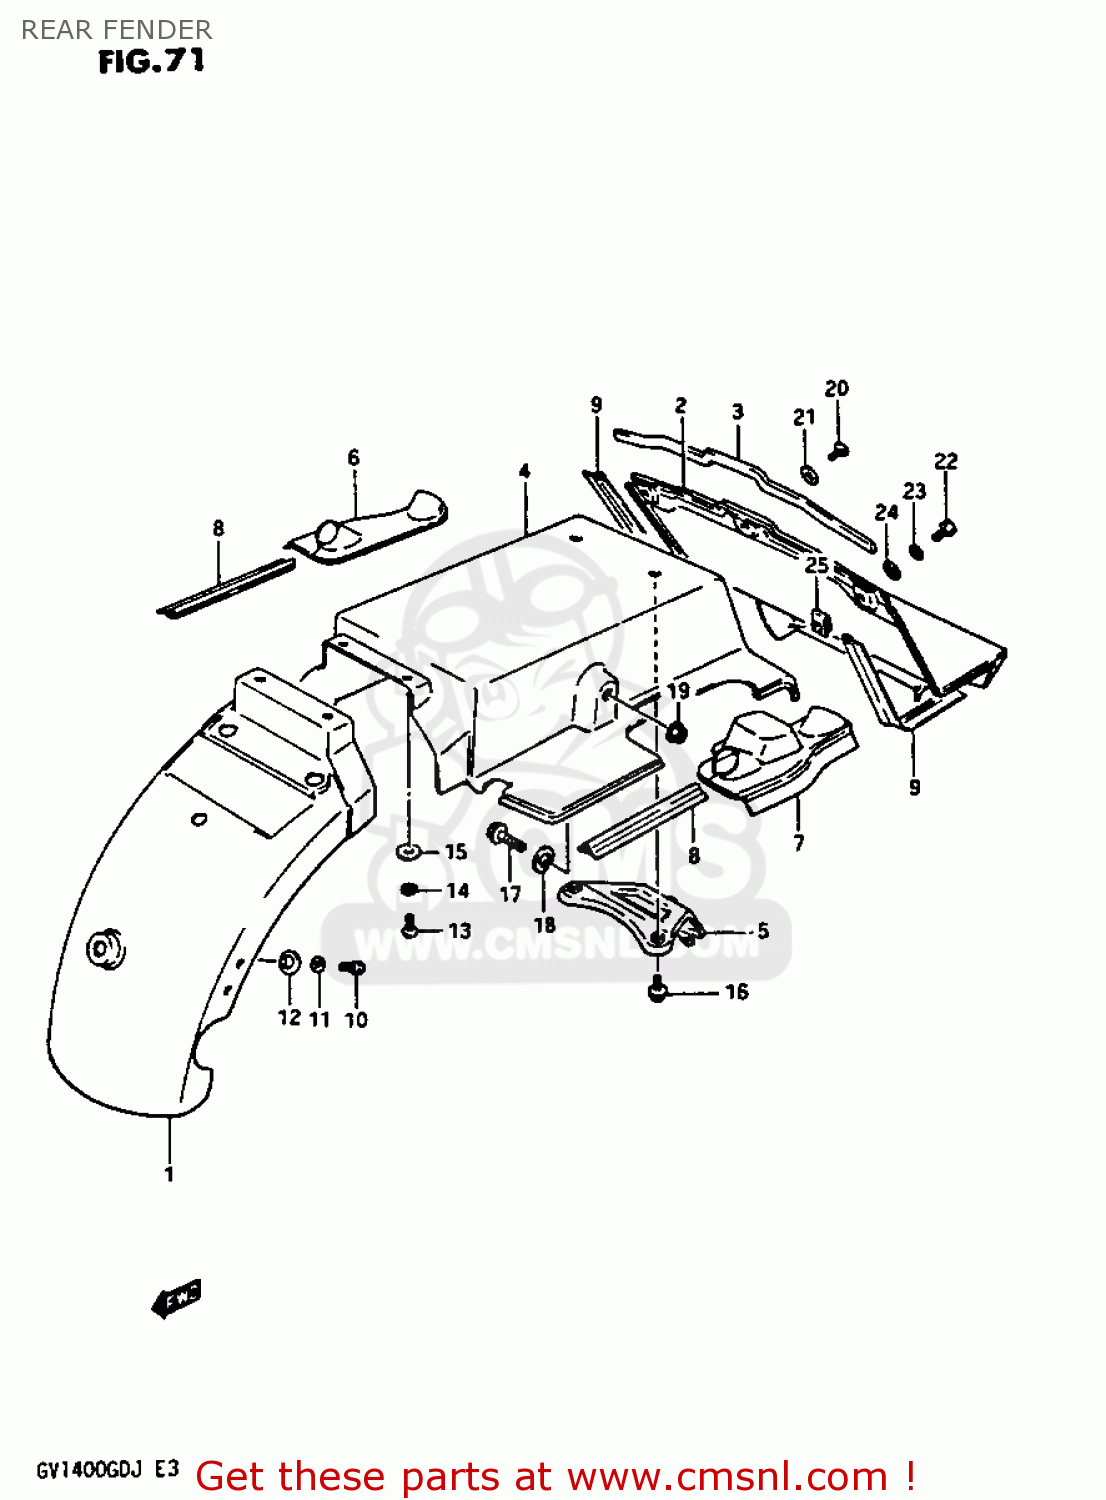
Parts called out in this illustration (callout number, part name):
1	BODY,REAR FENDER,FRONT
2	FENDER,REAR
3	SEAL,REAR FENDER,REAR
4	FENDER,REAR
5	REINFORCEMENT COMP,REAR FENDER
6	COVER,REAR FENDER SIDE,RIGHT
7	COVER,REAR FENDER SIDE,LEFT
8	WEATHER STRIP, CENTER
9	WEATHER STRIP, REAR
10	BOLT
11	WASHER,LOCK
12	WASHER
13	SCREW
14	WASHER,LOCK
15	WASHER
16	BOLT
17	BOLT 8X30
18	WASHER
19	NUT
20	SCREW
21	WASHER (5.5X14X1.2)
22	BOLT
23	WASHER,LOCK
24	WASHER
25	NUT
